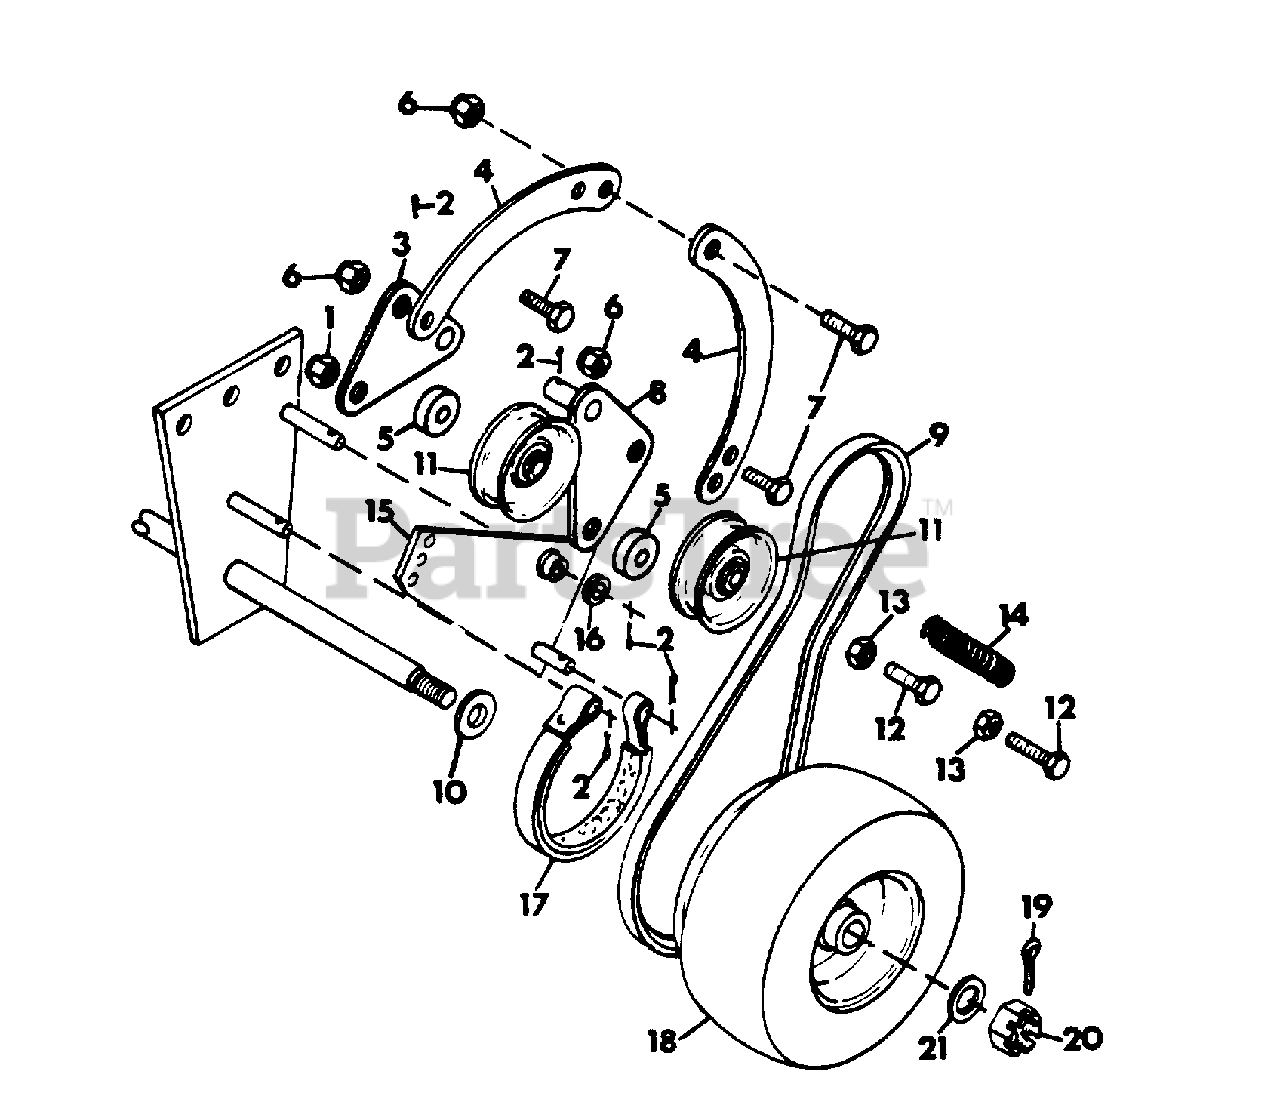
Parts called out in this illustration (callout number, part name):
1	NUT, LOCK 3/8-16
2	PIN, COTTER .09X.75
3	WELDMENT, WHEEL CLUTCH L.H.
4	STRAP, WHEEL CLUTCH ACTUATING
5	SPACER, IDLER
6	NUT, LOCK 5/16-18
7	BOLT, HEX 5/16-18X.625
8	LEVER, WHEEL CLUTCH R.H.
9	BELT, TRACTION
10	SPACER, WHEEL
11	SHEAVE, IDLER
12	BOLT, HEX 3/8-16X2.0
13	NUT, HEX 3/8-16
14	SPRING
15	WELDMENT, BRAKE LEVER L.H.
15	WELDMENT, BRAKE LEVER R.H.
16	WASHER, FLAT .344X.688X.065
17	ASSEMBLY, BRAKE BAND L.H.
17	ASSEMBLY, BRAKE BAND R.H.
18	ASSEMBLY, WHEEL AND TIRE
19	PIN, COTTER .156X1.50
20	NUT, SLOTTED 3/4-16
21	RACE, BEARING THRUST
